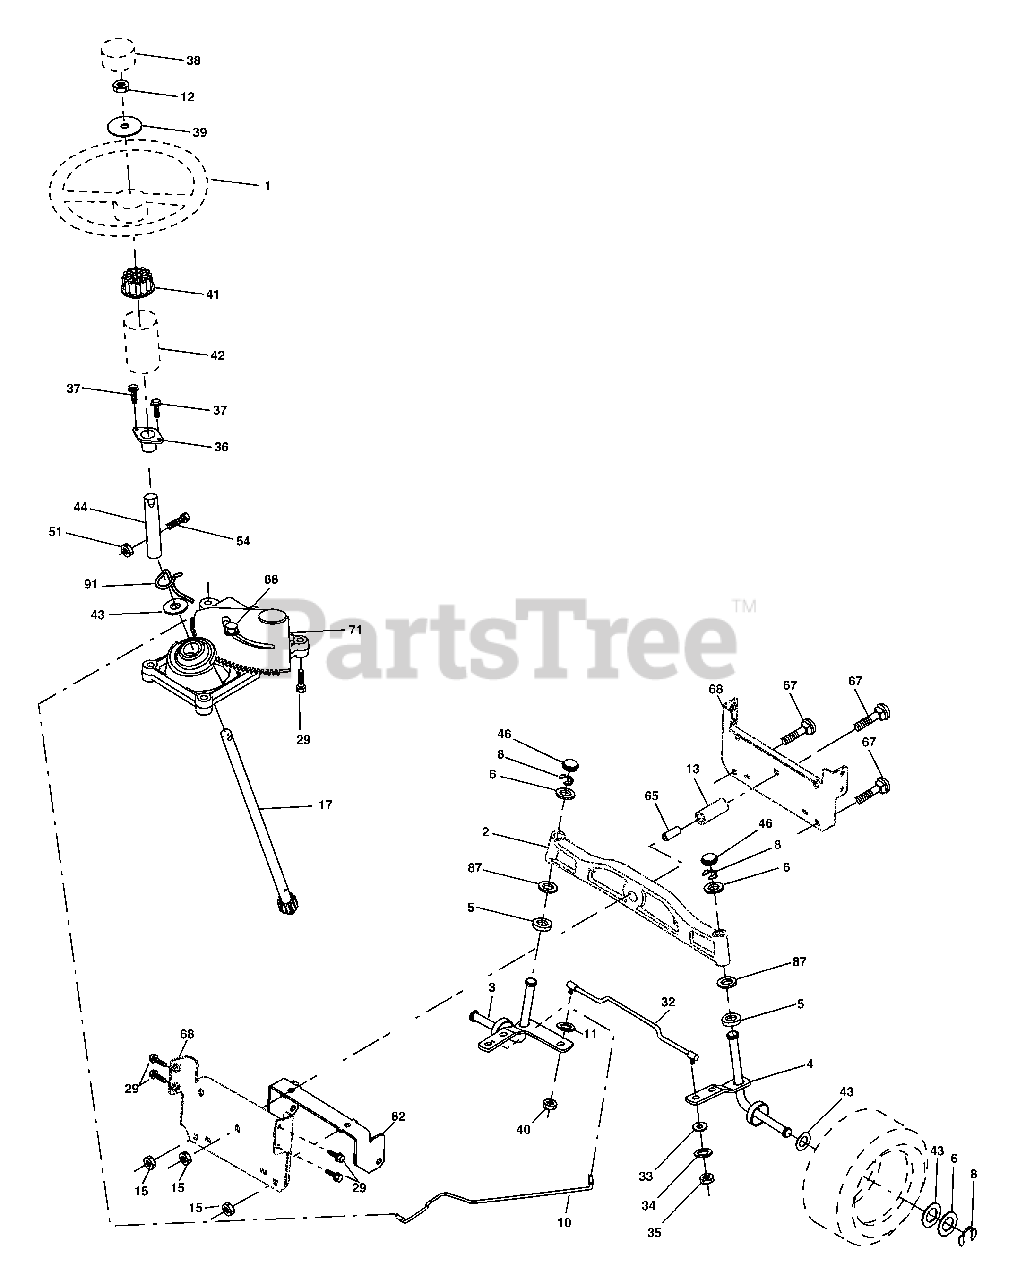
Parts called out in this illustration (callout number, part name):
1	Wheel Steering
2	Axle Asm Front
3	Spindle Asm Lh
4	Spindle Asm Rh
5	Bearing Race Thrust Harden
6	Washer 25/32 x 1 5/8 x 16 Ga.
8	Ring Klip #t5304-75
10	Link Drag Extended
11	Lockwasher
12	Nut Hex Jam Toplock 1/2-20 Unf
13	Spacer Bearing Axle Front
15	Hex Flange Lock
17	Shaft Asm Strg
29	Screw 3/8-16 x 3/4
32	Rod Tie
33	Washer 11/32 x 3/4 x 16 Ga.
34	Washer lock 5/16
35	Nut Crownlock 5/16-24
36	Bushing Strg 5/8 ID Dash
37	Screw TT #10-32 x 5 x 3/8 Flange
38	Insert Cap Strg
39	Washer 9/16 ID x 1-1/2 OD 11 Gr
40	Locknut Center
41	Adaptor Wheel Strg
42	Boot Dash Steering
43	Washer 25/32 x 1 1/4 x 16 Ga
44	Extension Steering
46	Cap Spindle Fr Top Blk
51	Nut Crownlock 1/4-28
54	Bolt Hex 1/4-28 Unf x 1-1/4 Gr. 8
65	Spacer Brace Axle
67	Bolt Rdhd Sq 3/8-16 Unc x 2-3/4
68	Brace Axle
71	Steering Asm
82	Bracket Susp Chassis Front
87	Washer Flat
88	Bolt Shoulder 7/16-20
91	Clip Steering
